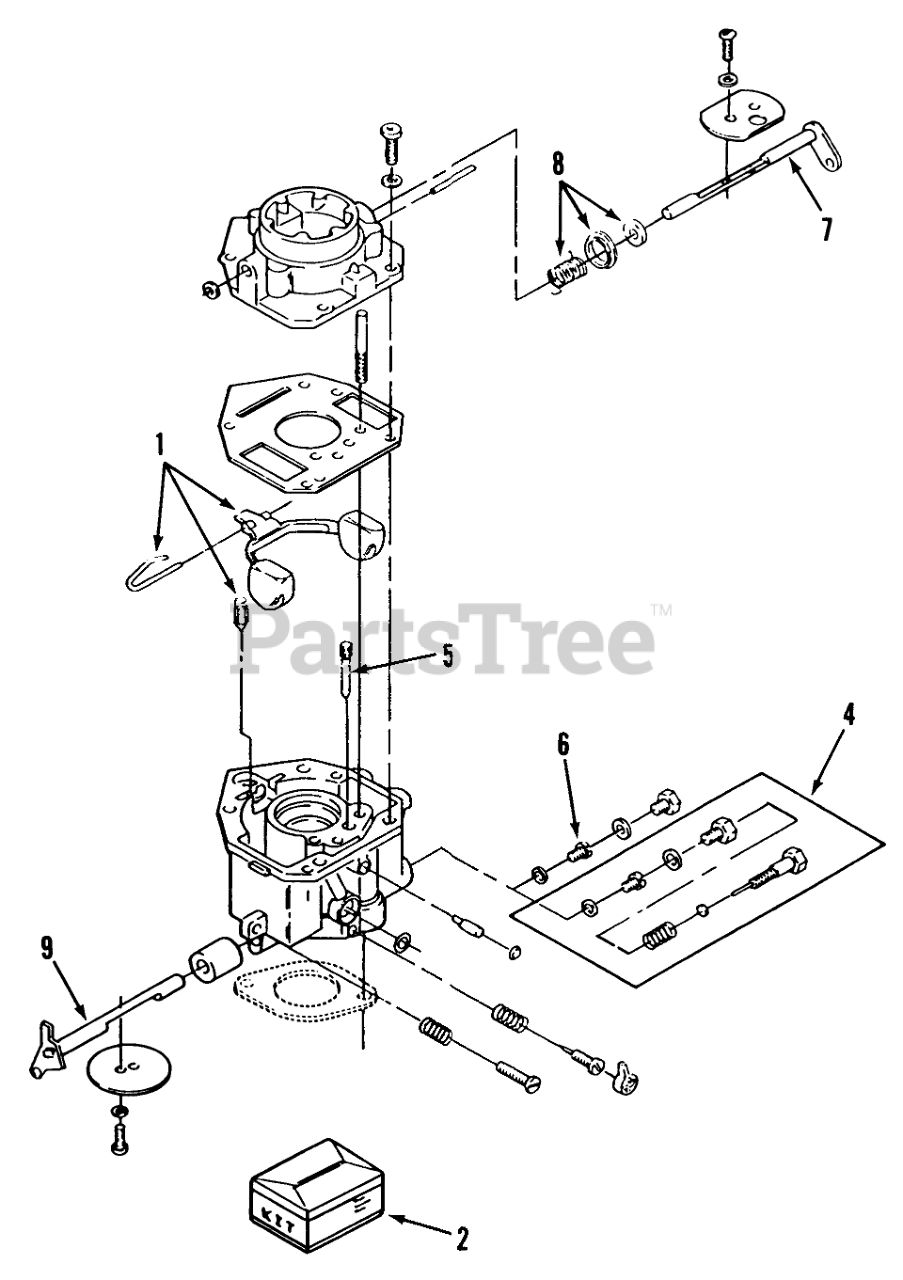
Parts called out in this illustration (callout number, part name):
1	Float Kit (Includes Float, Pin and Valve)
2	Repair Kit (Includes Screw and Plug Package, Gasket Package, Float Valve, Idle Adjustment Needle and Spring, Mounting Gaskets, Idle Limit Cap)
4	Power Jet
5	Idle Jet
6	Power Jet
7	Choke Shaft-Kit (Includes Choke Valve, Valve Set Screw & Air Filter)
8	Choke Lever-Kit (Includes Choke Lever Ring, Choke Spring & Choke Collar)
9	Throttle Shaft-Kit (Includes Valve Set Screw, Air Filter & Throttle Valve)
